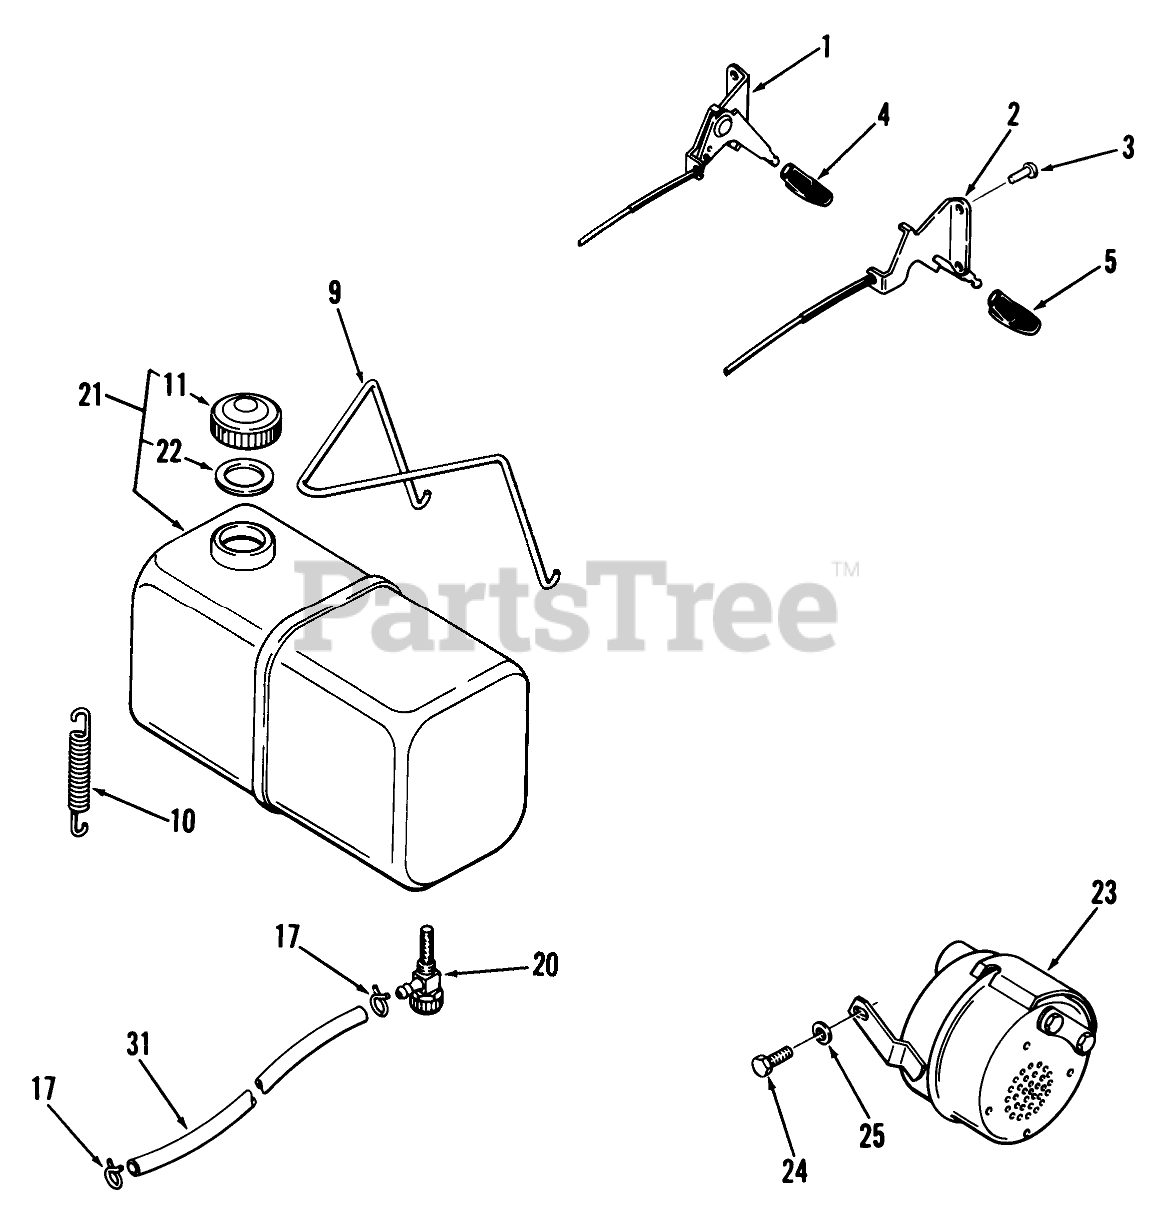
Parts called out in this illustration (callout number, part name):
1	CONTROL-THROTTLE
2	CONTROL-CHOKE
2	CONTROL THROTTLE
3	RIVET-4
4	KNOB-THROTTLE
5	KNOB-CHOKE
9	WIRE-HOLD DOWN
10	SPRING-EXTENSION
11	Gasoline Cap
17	Clamp
20	FILTER & VALVE ASSY
21	Fuel Tank Assy
22	Seal (Service Only)
23	ASSY-MUFFLER
24	Bolt
31	Hose-Fuel-Pump to Carb. 3"
31	Fuel Hose 18"
